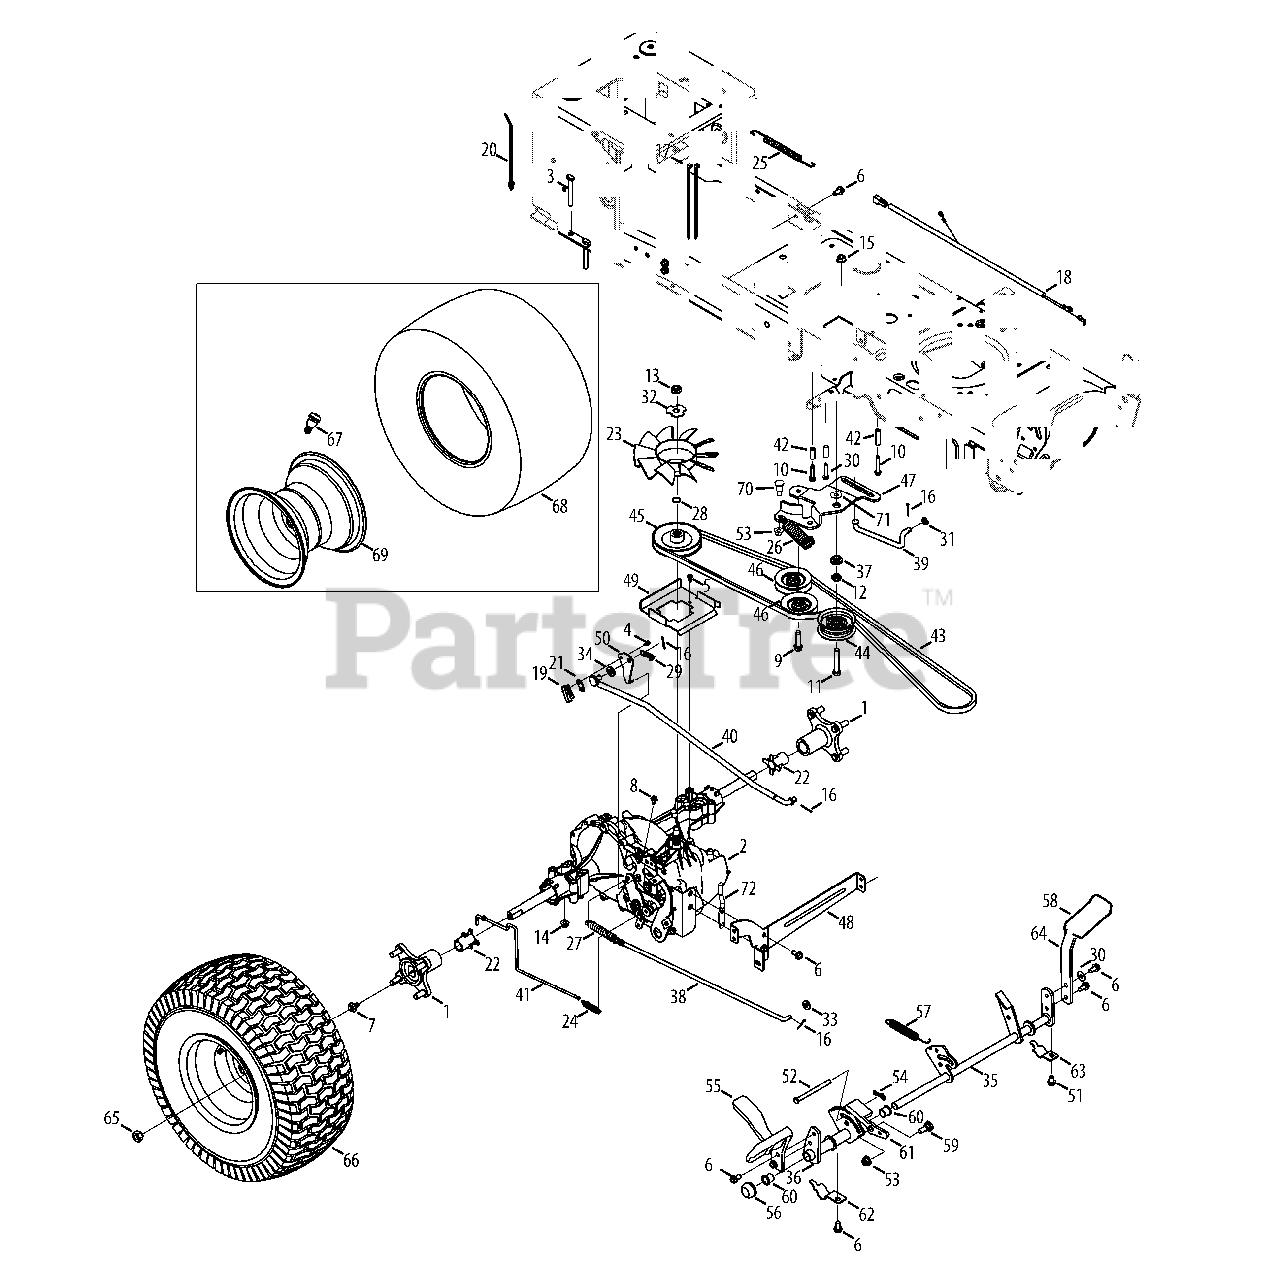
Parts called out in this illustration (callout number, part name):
1	Wheel Hub Assembly
2	Hydro Transmission
3	Hex Head Screw, 5/16-18:2.75
4	Screw, Indented Washer, #8-18:0.500
5	Screw, #10-16:0.500
6	Taptite Screw, 5/16-18:.750
7	Screw, 5/16-24 x .750
8	Taptite Screw, 1/4-20:0.375
9	Taptite Sems Screw, :3/8-16:1.500
10	Taptite Screw, 1/4-20:1.625
11	Hex Head Screw, 3/8-16:2.25
12	Jam Nut, 7/16-20
13	Jamlock Nut, 1/2-20
14	Flangelock Nut, 5/16-18
15	Flangelock Nut, 3/8-16
16	Cotter Pin, 3/32:1.0
17	Cable Tie. 3/16 x .05 x 7.4
18	Jumper Harness
19	Short Spring Switch
20	Push Mount Cable Tie 7.5 LG
21	Insulator Nut Plate
22	Sleeve, .765 ID x 1.500 LG
23	Hydro Fan
24	Extension Spring, .48 OD x 2.03
25	Extension Spring, .500 DIA x 12.6 LG
26	Extension Spring, 1.00 DIA x 4.75
27	Extension Spring, .59 OD x 4.00 LG
28	Wire Ring
29	Extension Spring, .375 OD x 1.44 LG
30	Screw, Self Tapping, 1/4-20 x 1.75
31	Flat Washer, .330 x .630 x .0635
32	Lock Washer
33	Flat Washer, .344 x .750 x .120
34	Flat Washer, .407 x .812 x .135
35	Brake Control Assembly
36	Hydro Pedal Bracket Assembly
37	Shoulder Spacer, 1.375 x .380 x .183
38	Brake Rod
39	Footpedal Bypass Transmission Rod
40	Hydro Control Rod
41	Hydro Bypass Rod
42	Spacer, 260 x .372 x 1.420 LG
43	V-Belt, 4L x 78.9 POLY
44	Flat Idler Pulley, 2.75 OD
45	Input Pulley, 4.13 DIA
46	V Idler Pulley, x 3.06
47	Center Idler Bracket
48	Hydro Mounting Bracket
49	Belt Disengage Support Bracket
50	Switch Actuator Bracket
51	Taptite Screw, 5/16-18:0.625
52	Clevis Pin, 5/16 x 3.985
53	Flangelock Nut, 3/8-16
54	Bow-Tie Cotter Pin
55	Control Pedal
56	Push Cap
57	Extension Spring, .63 DIA x 4.95 LG
58	Brake Pedal Pad
59	Shoulder Bolt, .500 x .270:3/8-16
60	Flange Bearing, .630 ID x .695 OD x .60
61	Cruise Latch
62	Pedal Support Bracket
63	Pedal Support Bracket, 5/8
64	Brake Pedal Bracket
65	Lug Nut
66	Wheel Assembly
67	Tubeless Air Valve
69	Rim Assembly
70	Screw Shldr, .50 x .685 3/8-16
71	Washer, Flat, .385 x 1.0 x .030
72	Belt Keeper Rod
